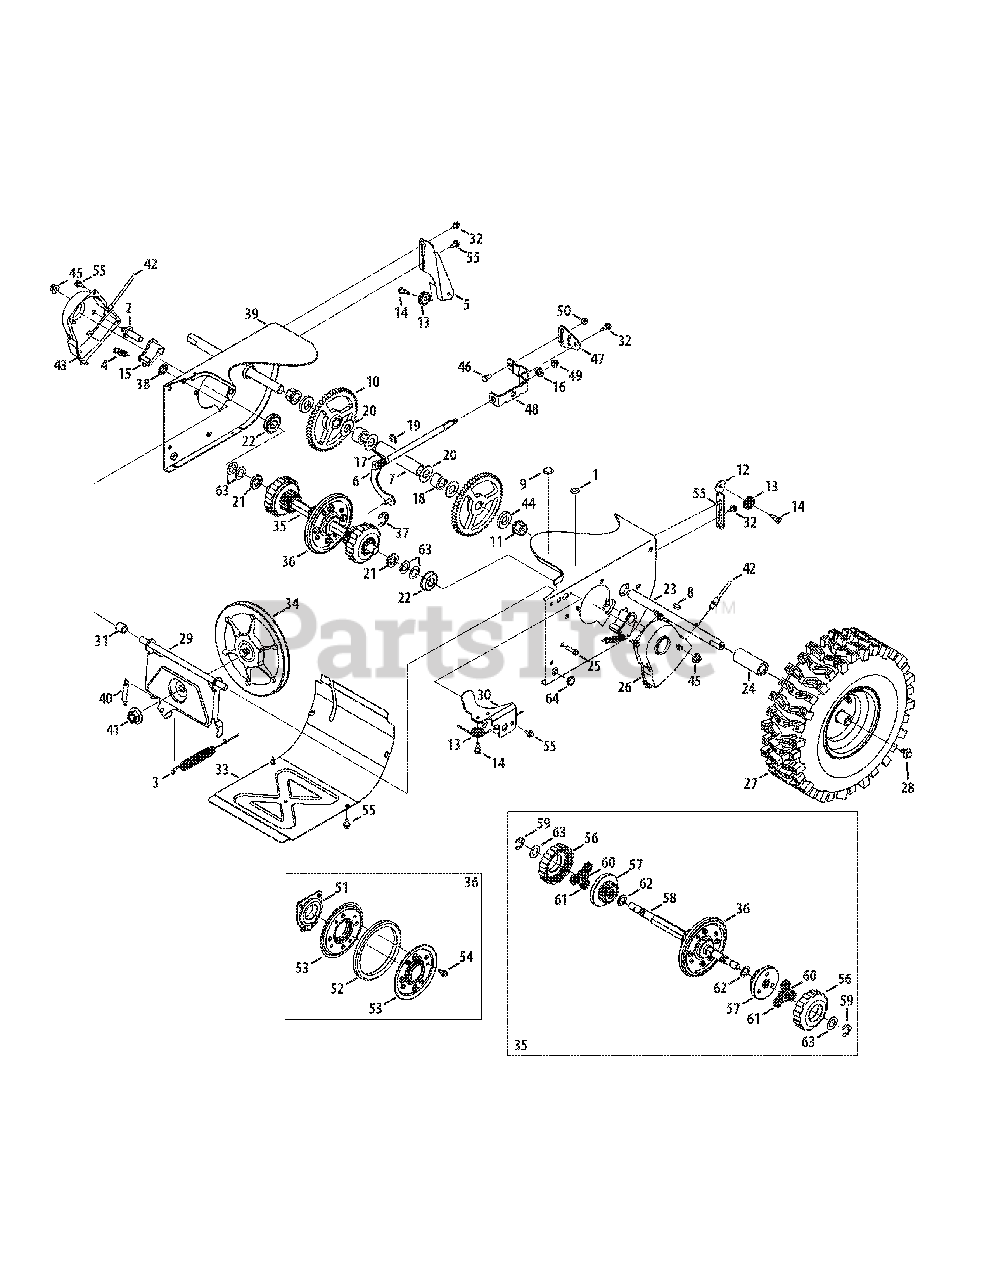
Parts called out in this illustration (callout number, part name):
1	Plug, 3/8 ID
2	Actuator Shaft
3	Drive Clutch Cable
4	Extension Spring
5	Drive Clutch Cable Guide Bracket
6	Shift Rod Assembly
7	Axle Support Tube
8	Hi Pro Key
9	Plug, 1/2 ID
10	Gear, 56T
11	Hex Flange Bearing
12	Auger Clutch Cable Guide Bracket
13	Cable Roller
14	C Screw, 1/4-28 x 0.375
15	Dogg Assembly - LH
15	Dogg Assembly - RH
16	Washer, Flat
17	Torsion Spring, .750 ID x .968 Lg.
18	Spacer
19	E Ring
20	Flat Washer, .76 x 1.49 x .06
21	Spacer
22	Ball Bearing
24	Spacer
25	TT Screw, 1/4-20 x 1.0
26	Shaft Retainer - LH
27	Wheel Complete - LH
27	Wheel Complete - RH
28	Screw, 5/16-24 x 0.75
29	Friction Wheel Support Brkt. Assy.
30	Auger Cable Guide Bracket
31	Spacer
32	Shoulder Screw
33	Frame Cover
34	Friction Wheel Disc Assembly
35	Drive Shaft Assembly
36	Friction Wheel Assembly
37	Retainer Ring
38	Speed Nut
39	Wheel Drive Frame
40	Extension Spring
41	Flange Nut, 5/8-18
42	Steering Cable
43	Shaft Retainer - RH
44	Axle Spacer
45	Flange Lock Nut, 3/8-16
46	Hex Screw, 1/4-20 x .620
47	Speed Selector Pivot Bracket
48	Speed Selector Shift Bracket
49	Flange Lock Nut, 5/16-18
50	Flange Lock Nut, 1/4-20
51	Friction Wheel Bearing Assembly
52	Friction Wheel
53	Friction Plate
54	Screw, 5/16-18 x .750
55	AB Screw, 1/4-20 x 0.625
56	Gear Assembly, Plantry Ring
57	Carrier Assembly, Plantry Ring
58	Shaft, Strbl Drv Hex, .812
59	E-Ring
60	Gear, Sun, 18T
61	Gear, 12T
62	Washer, Thrust, .75 x 1.25 x .03
63	Washer, Flat, .67 x 1.174 x .02
